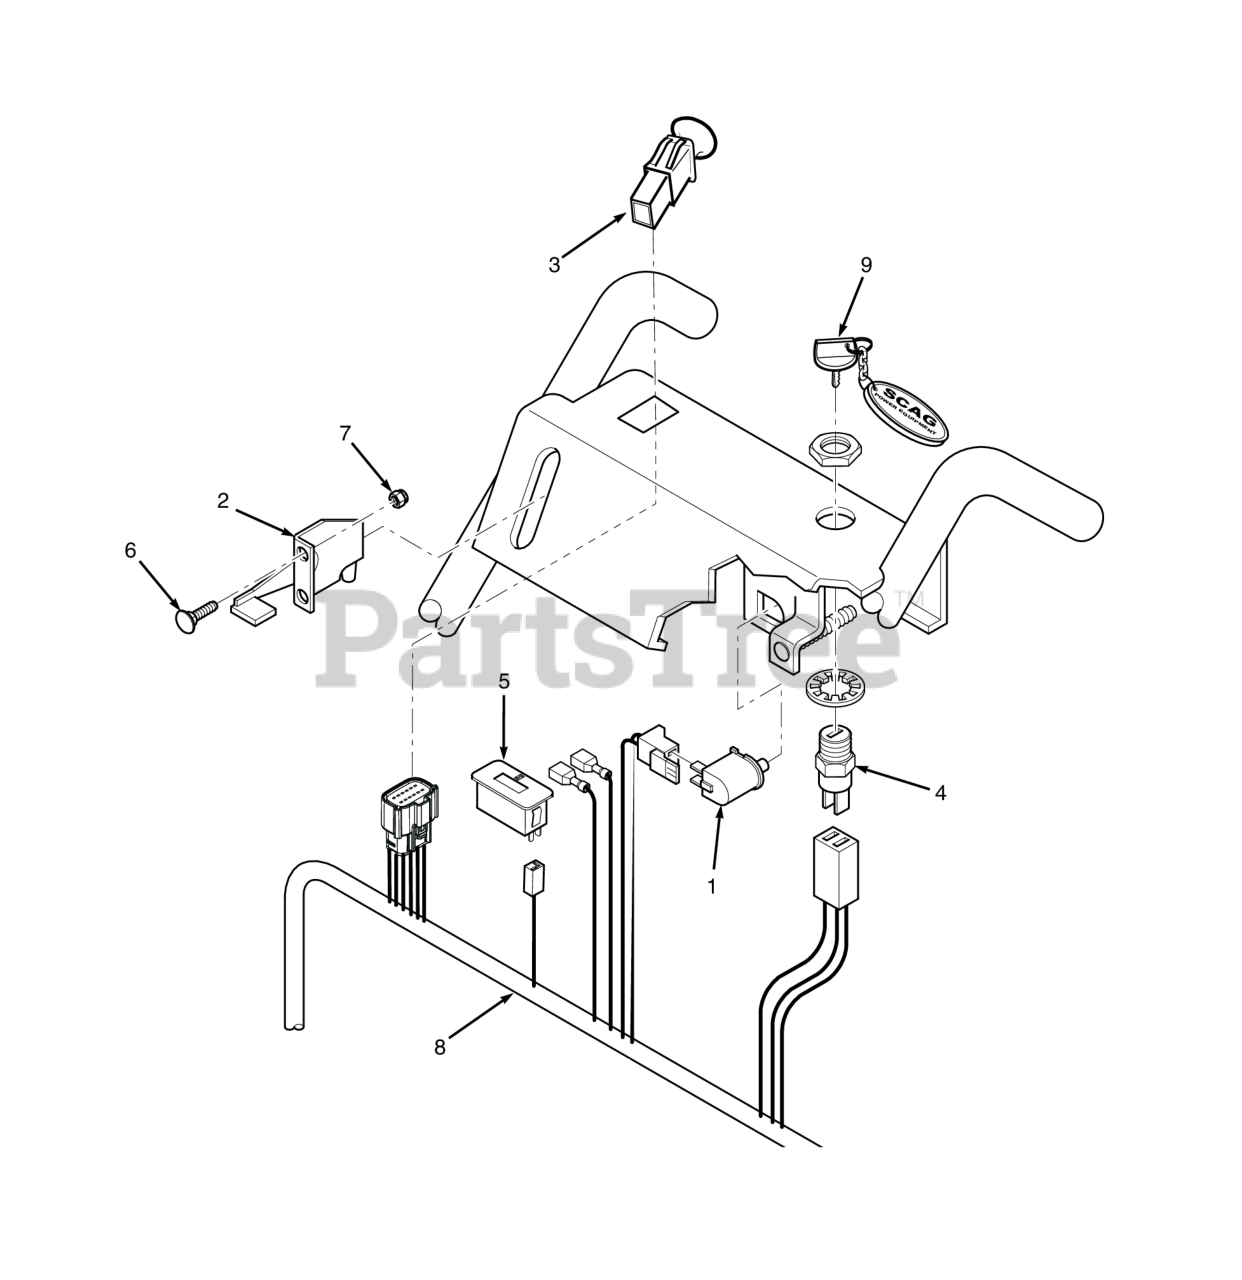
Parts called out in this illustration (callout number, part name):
1	SWITCH, NEUTRAL INTERLOCK
2	Throttle Control (15KA & 17KA)
3	Switch, PTO - 10 Amp
4	KEY SWITCH, MANUAL SRT.(INCL. HWD)
5	Hour Meter, Inductive
6	Bolt, Carriage #10-24 x 1/2"
7	Nut, Elastic Stop #10-24
8	Handle Wire Harness, Manual Start
9	Key, Assembly w/Fob
